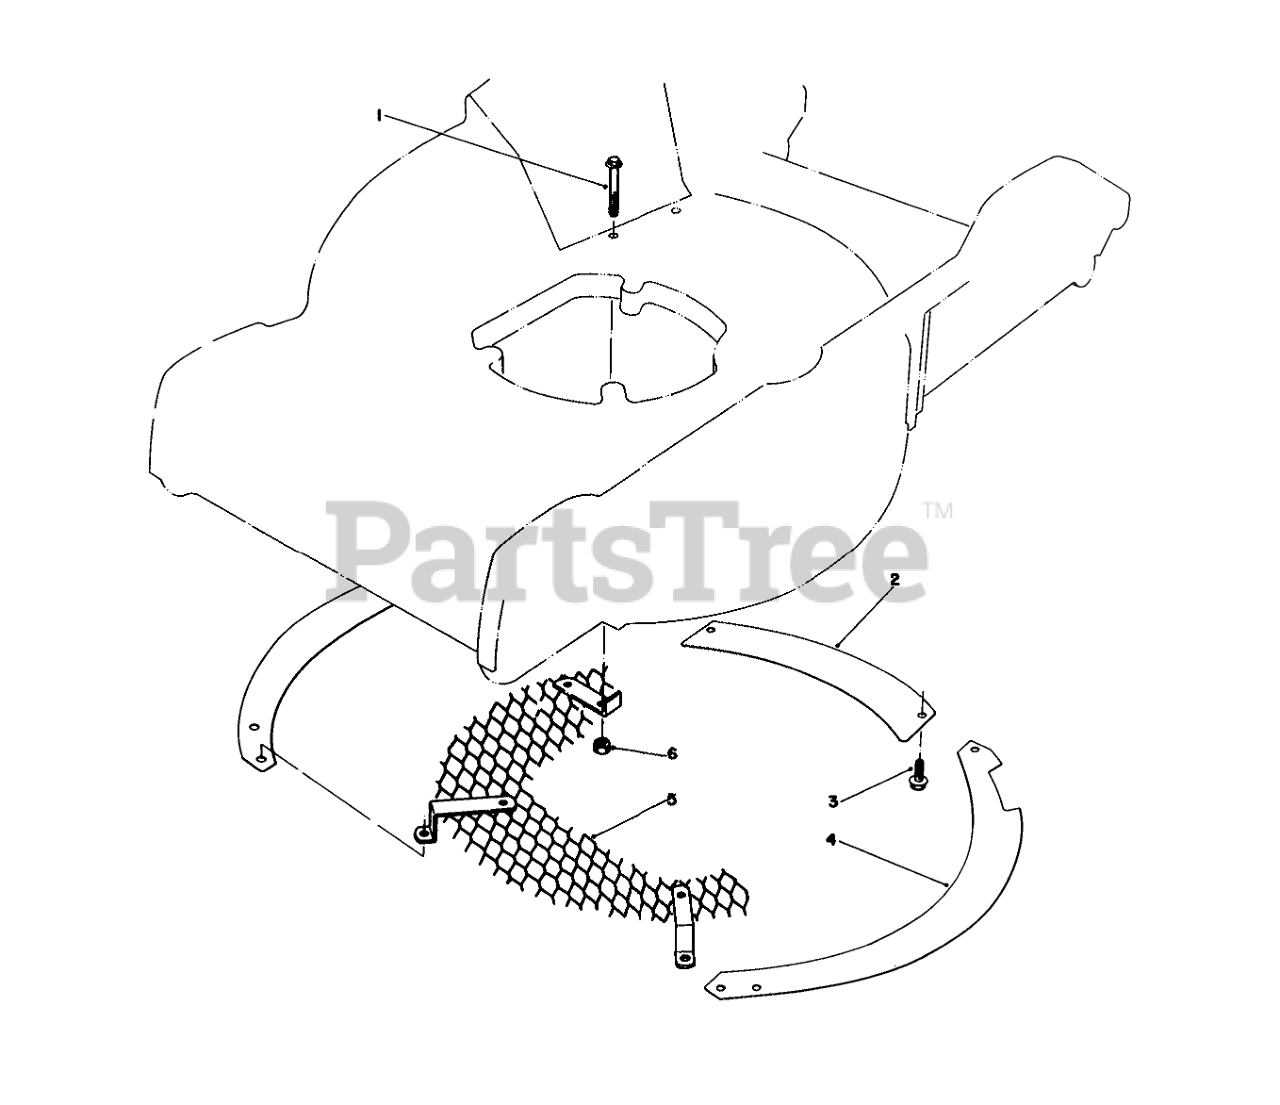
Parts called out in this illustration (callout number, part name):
1	Screw
2	Rear Baffle
3	SCREW
4	Outer Baffle
5	Screen
6	NUT-HEX, SIDE DEFORM
